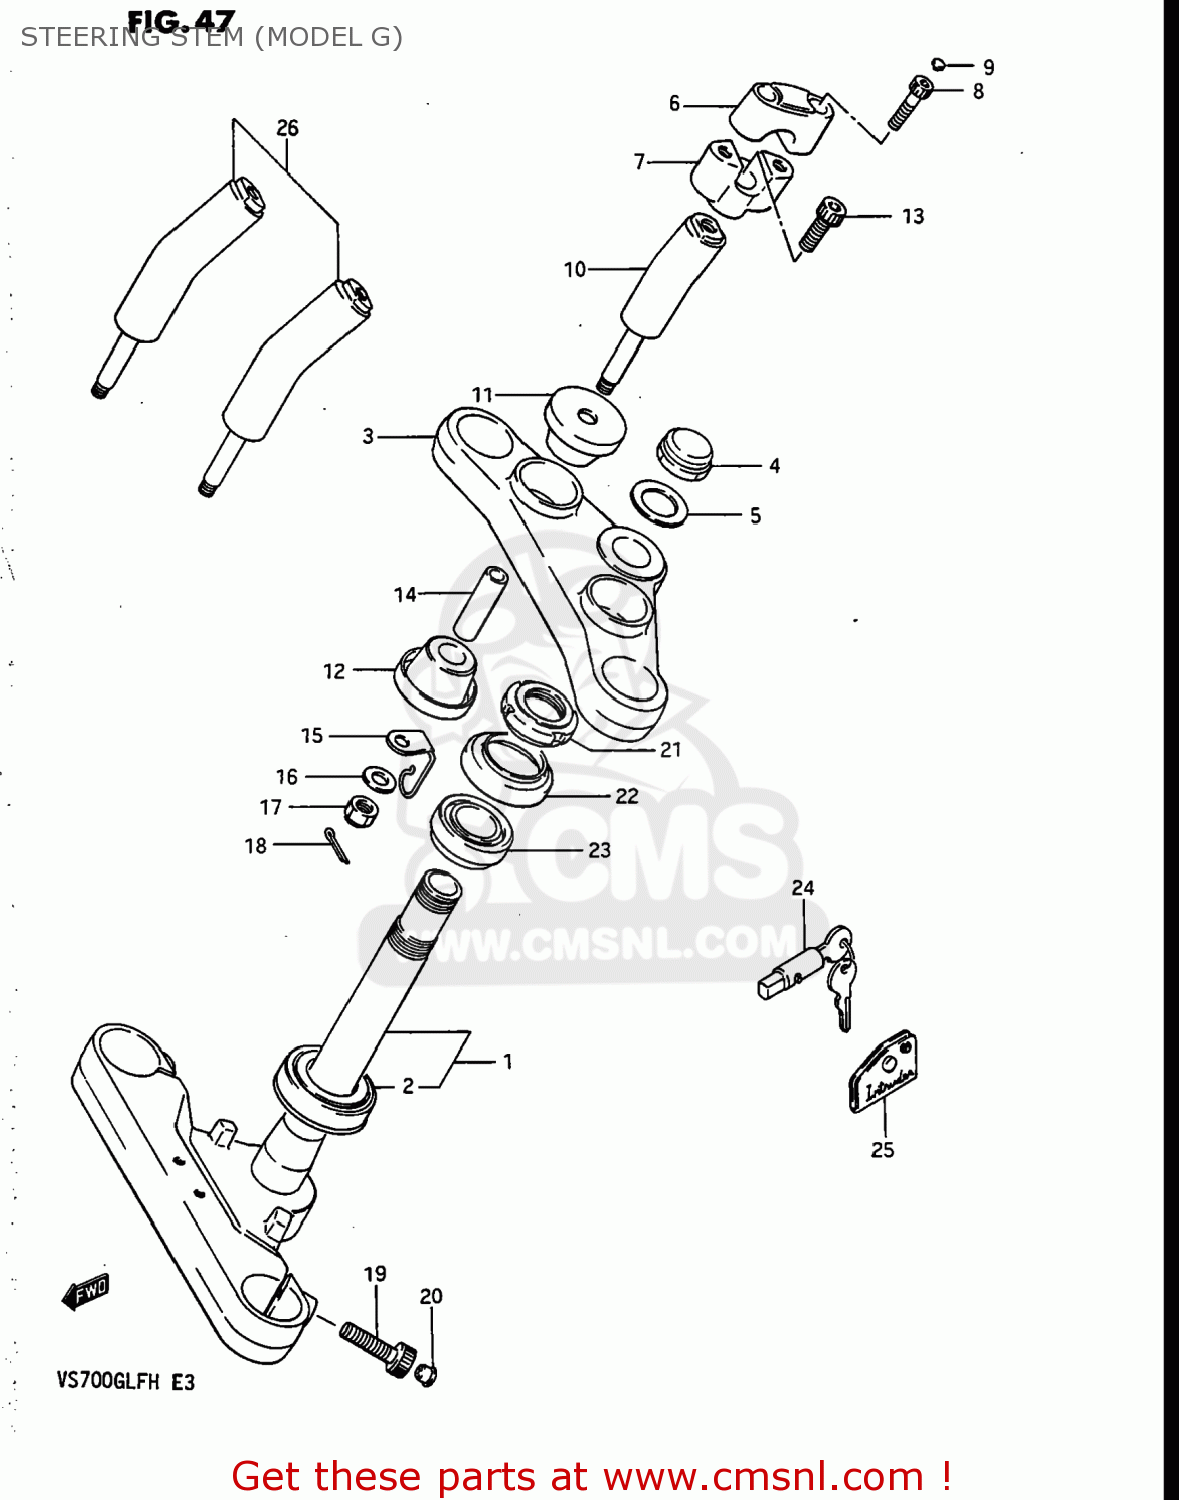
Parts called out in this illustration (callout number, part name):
1	STEM,STEERING
2	BEARING
3	HEAD,STEERING STEM
4	NUT,STEM HEAD
5	WASHER
6	HOLDER,HANDLEBAR
7	HOLDER,HANDLEBAR
8	BOLT, REAR (8X30)
9	CAP(OD:14.5)
10	STAY,HANDLE
11	CUSHION
12	CUSHION,LWR
13	BOLT
14	SPACER(10.2X14X46)
15	CLAMP,SPEEDOMETER CABLE
16	WASHER 10MM
17	NUT
18	PIN 20X20
19	BOLT,STEERING STEM HEAD
20	CAP(OD:12)
21	NUT,STEERING STEM(25X44X10)
22	DUST SEAL,STEERING,UPPER
23	TAPER,ROLLER BEARING
24	LOCK ASSEMBLY,STEERING (NEI
25	CASE,STEERING KEY
26	STAY SET,HANDLE
